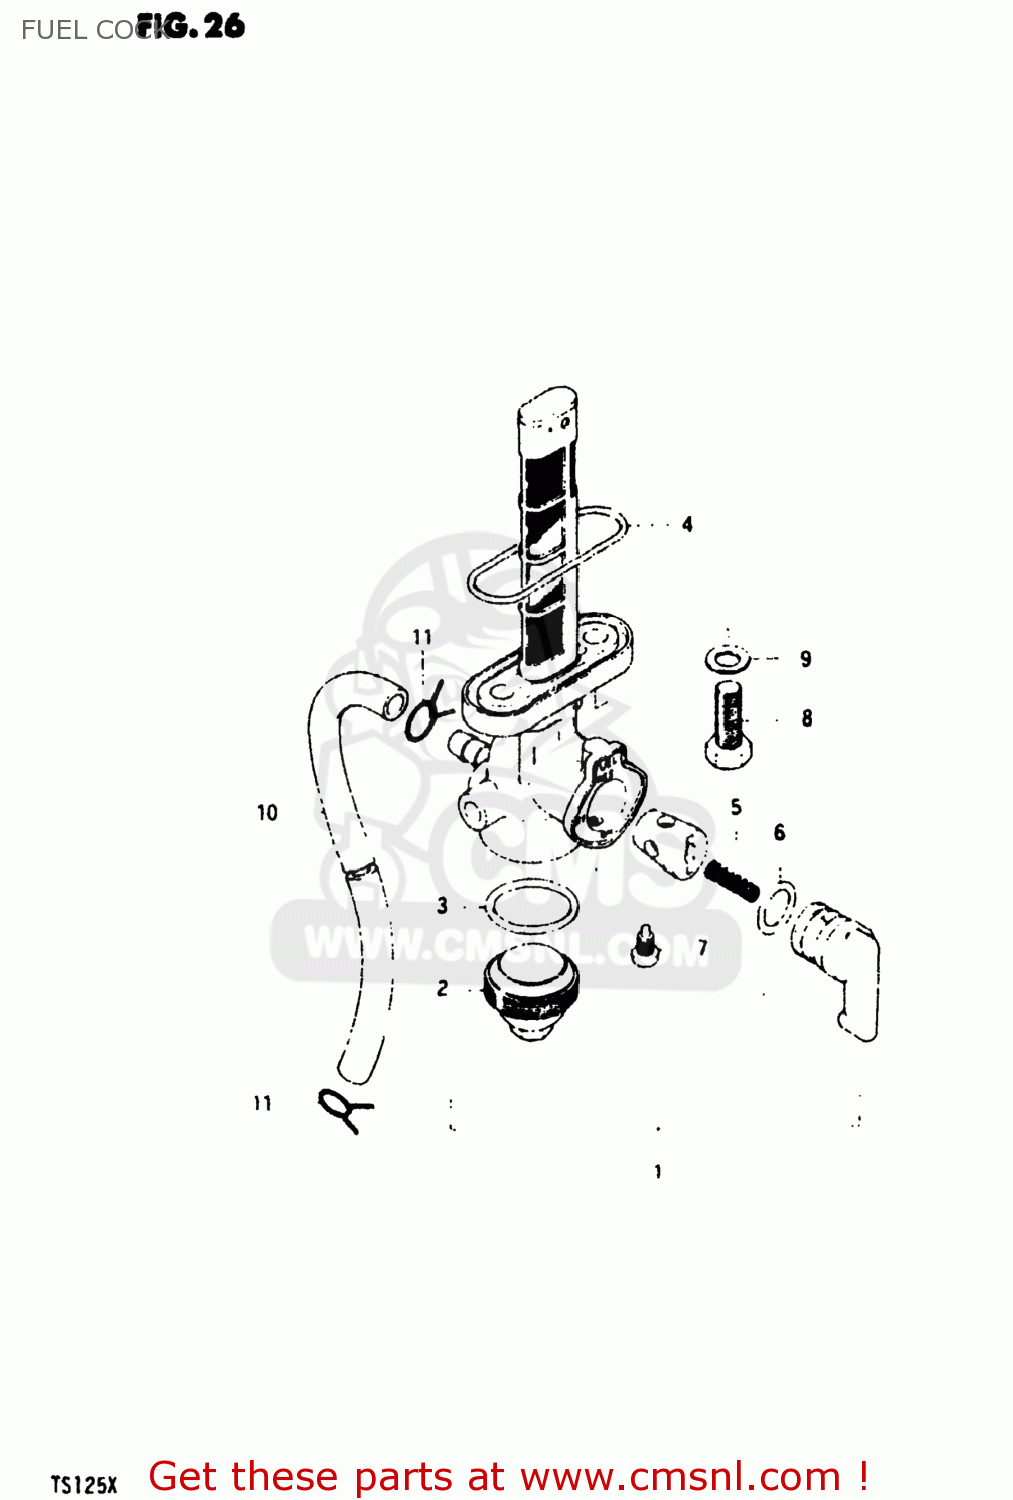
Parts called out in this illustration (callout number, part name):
1	COCK ASSEMBLY,FUEL
2	CUP,STRAINER
3	GASKET,FILTER (NAS)
4	O RING,FUEL COCK
5	SPRING
6	O-RING
7	SCREW
8	BOLT(6X20)
9	GASKET
10	HOSE
11	CLIP
